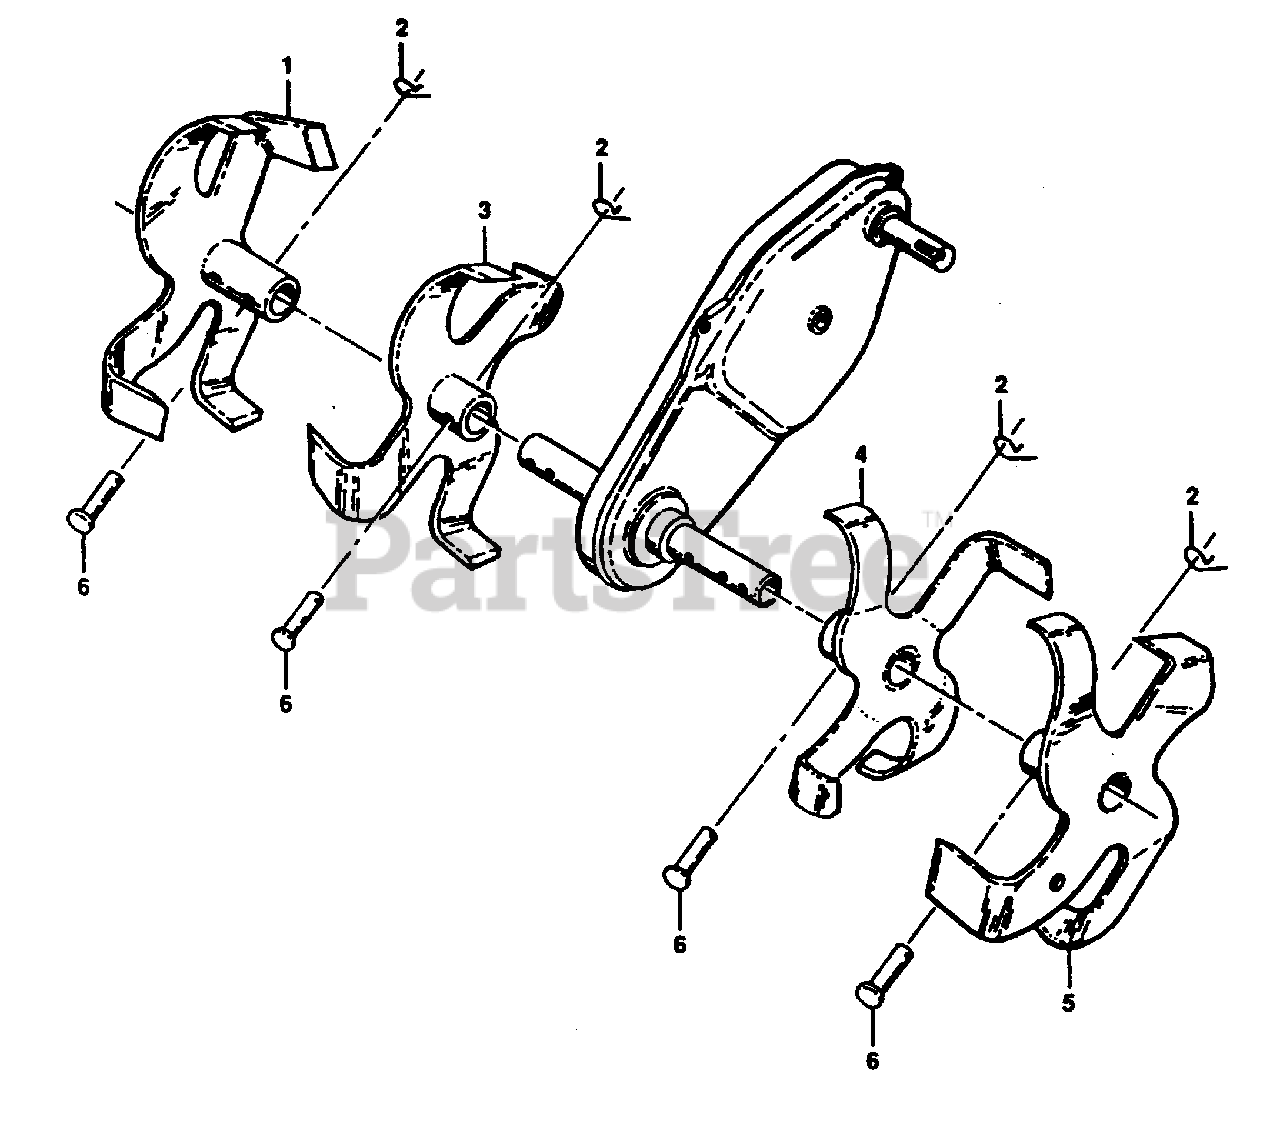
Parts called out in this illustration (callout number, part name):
1	Tine, Outer, R.H. (AYP part number)
2	Clip, Hairpin (AYP part number)
3	Tine, Inner, R.H. (AYP part number)
4	Tine, Inner, L.H. (AYP part number)
5	Tine, Outer, L.H. (AYP part number)
6	Pin, Clevis (AYP part number)
